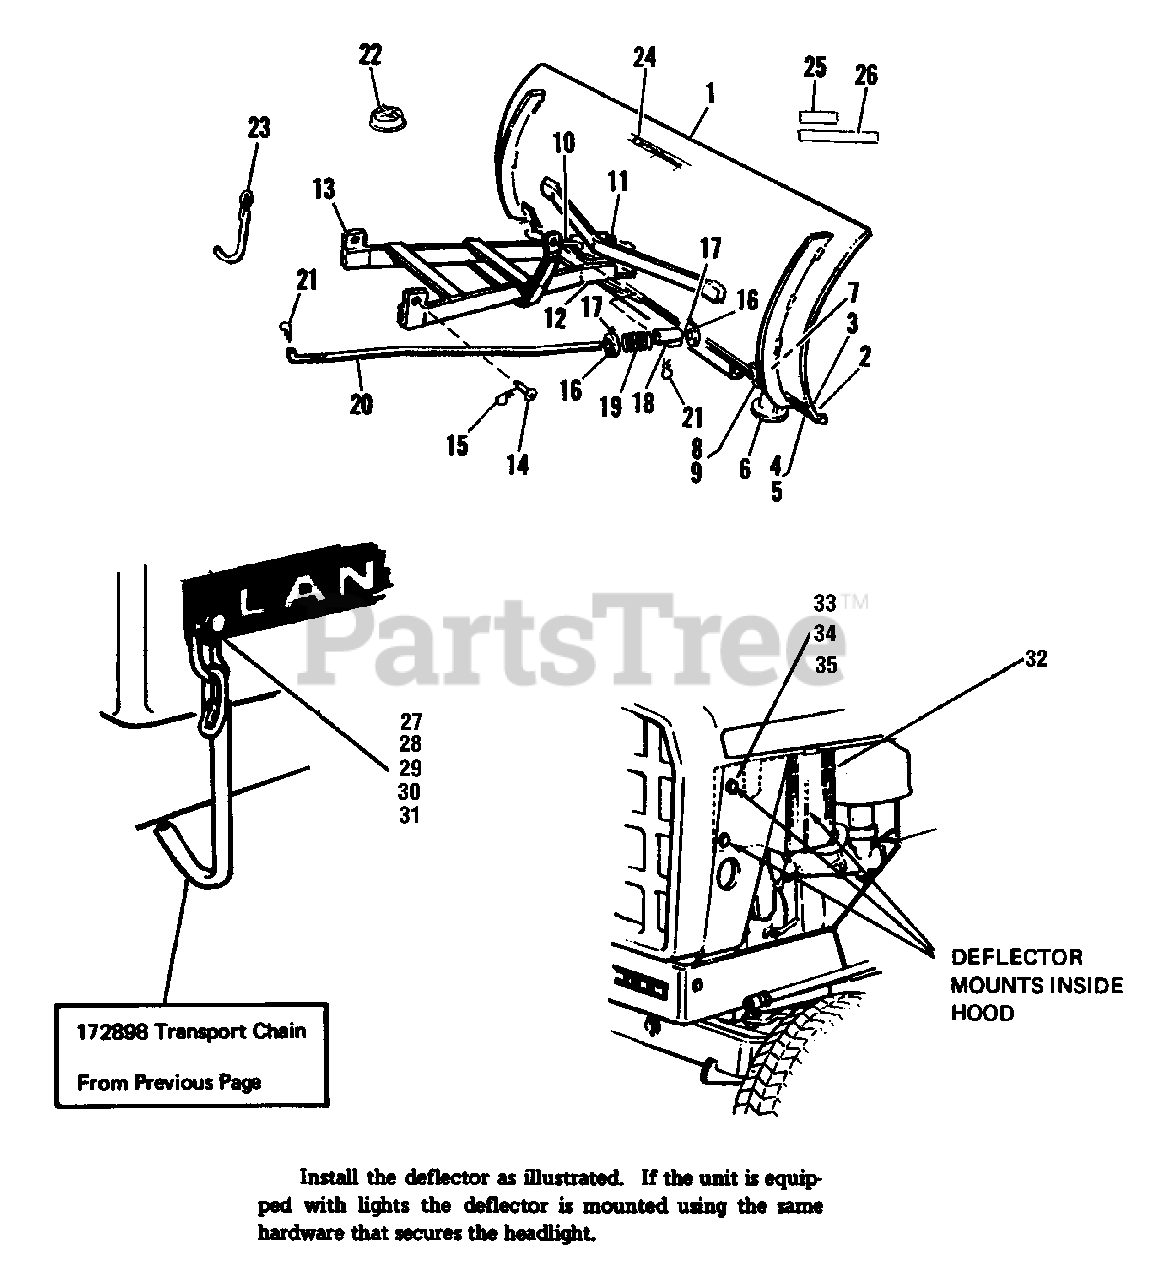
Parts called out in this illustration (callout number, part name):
1	42" Blade Assembly
2	Wear Plate
3	Carriage Bolt, 3/8"-16 x 3/4"
4	Lock Washer, 3/8"
5	Hex Nut, Full, 3/8"-16
6	Shoe Assembly
7	Carriage Bolt, 3/8"-16 x 1"
8	Lock Washer, 3/8"
9	Hex Nut, Full, 3/8"-16
12	Spring Clip
13	Push Bar Assembly
14	Pin
15	Hairpin Clip
16	Collar
17	Set Screw, 5/16"-18 x 3/8"
20	Front Lift Rod
21	Hairpin Clip
22	Fuel Tank Cap (Winterized)
23	Transport Chain Assembly
24	Film, Simplicity
25	Model No. Plate
26	Decal, Instructions
27	Hex Capscrew, 3/8"-16 x 1-1/2"
29	Plain Washer, 3/8"
30	Lock Washer, 3/8"
31	Hex Nut, Full, 3/8"-16
32	Deflector
33	Hex Capscrew, 1/4"-20 x 1/2"
34	Lock Washer, 1/4"
35	Hex Nut, 1/4"-20
